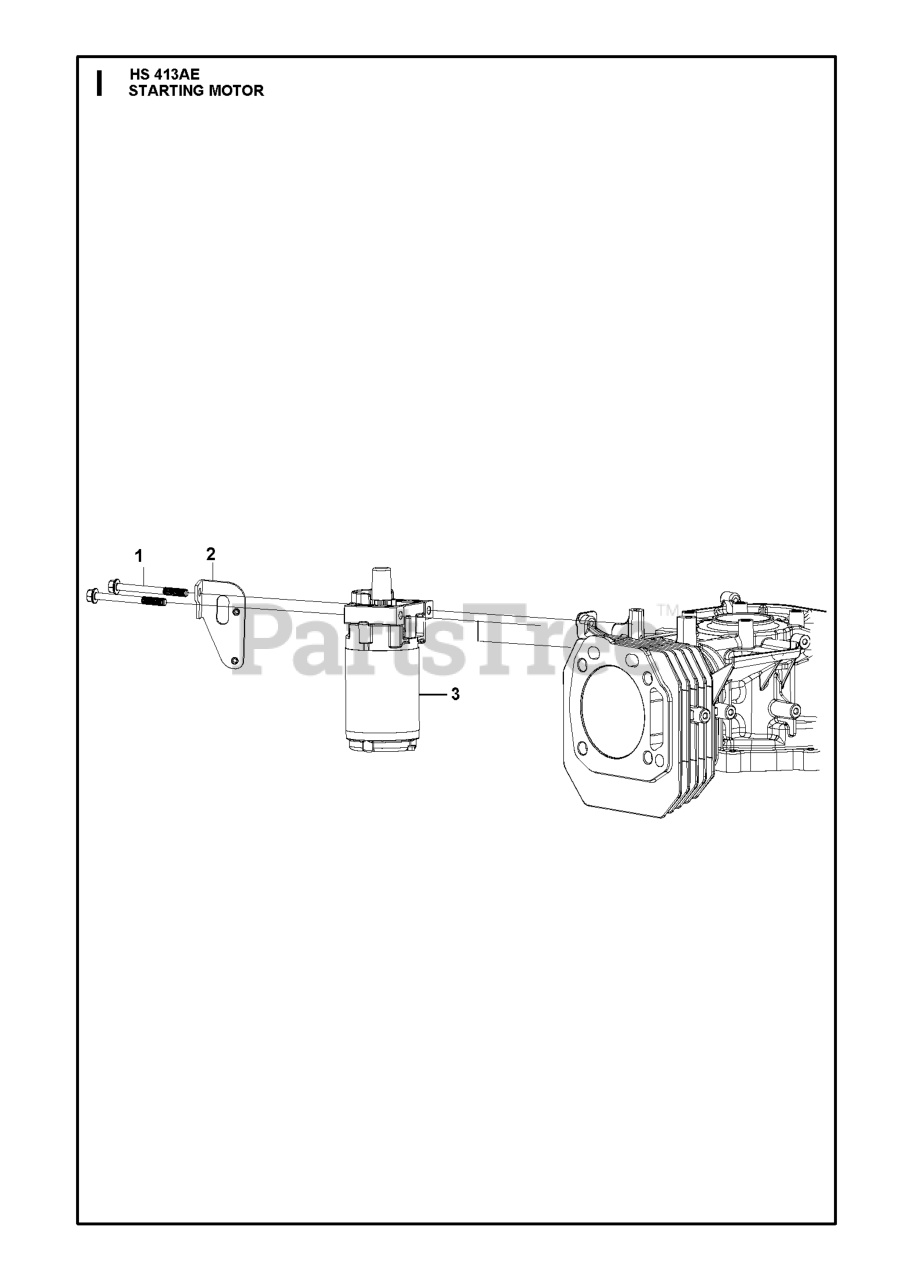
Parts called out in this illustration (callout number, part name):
1	BOLT GB/T 5789: M8 L=80 S=12
2	SUPPORT RECTIFIER SUPPORT
3	STARTER MOTOR
